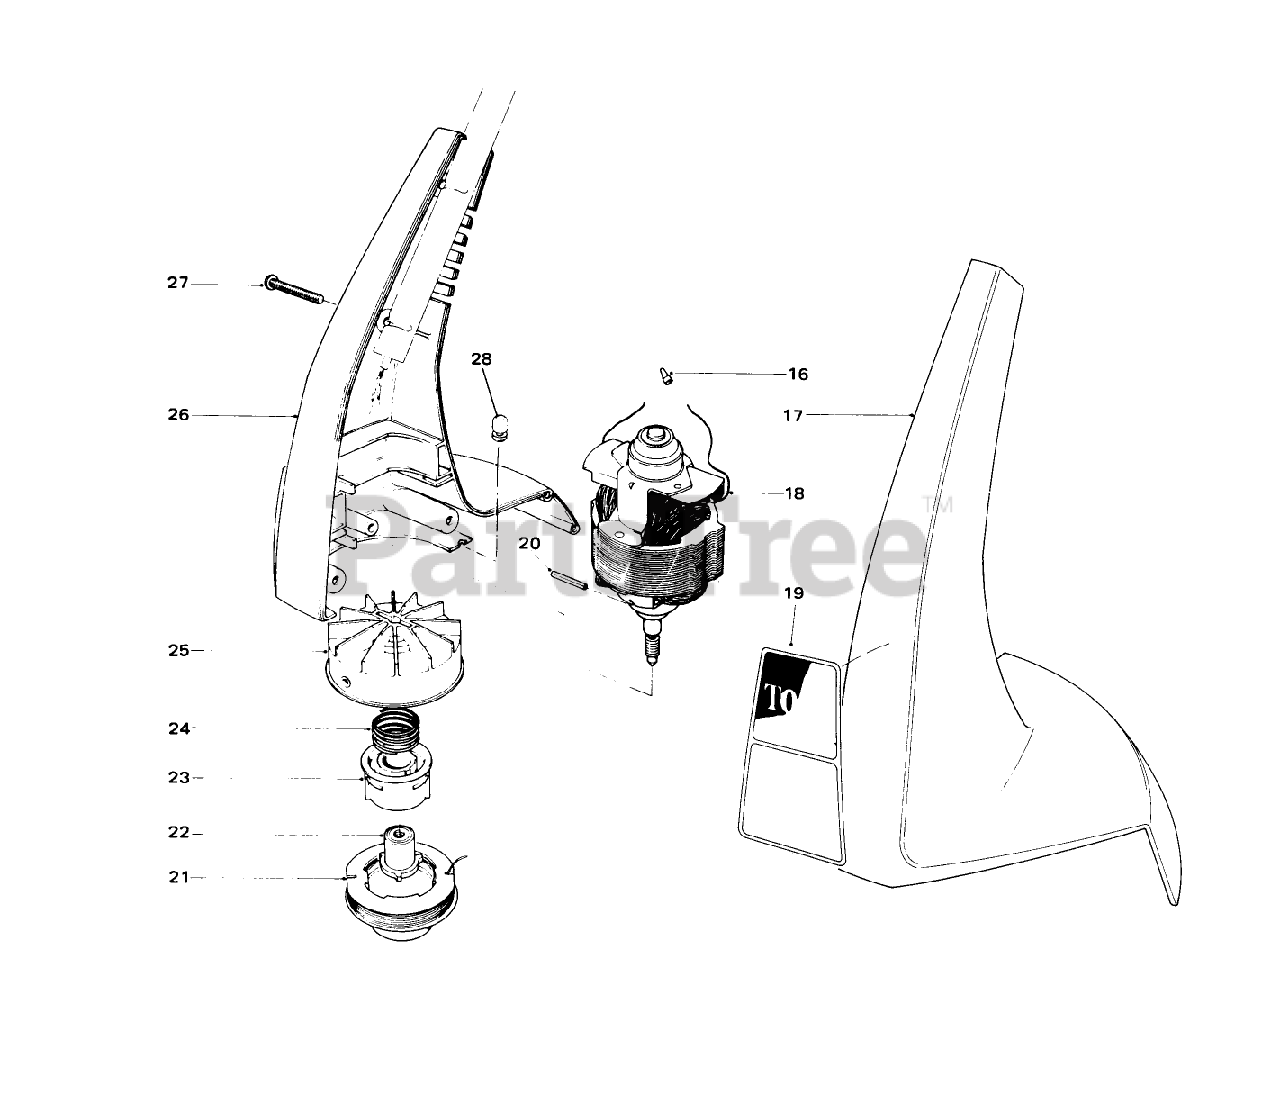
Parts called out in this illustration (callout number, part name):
16	CONNECTOR WIRE JOINT
17	LH HOUSING
18	Motor
19	Decal
20	COIL PIN
21	Prewound Spool Cap
22	Driver
23	CORE - SPOOL
24	SPRING-COMPRESSION
25	FAN HUB ASM
26	RH HOUSING ASM
27	Screw
28	GROMMET
